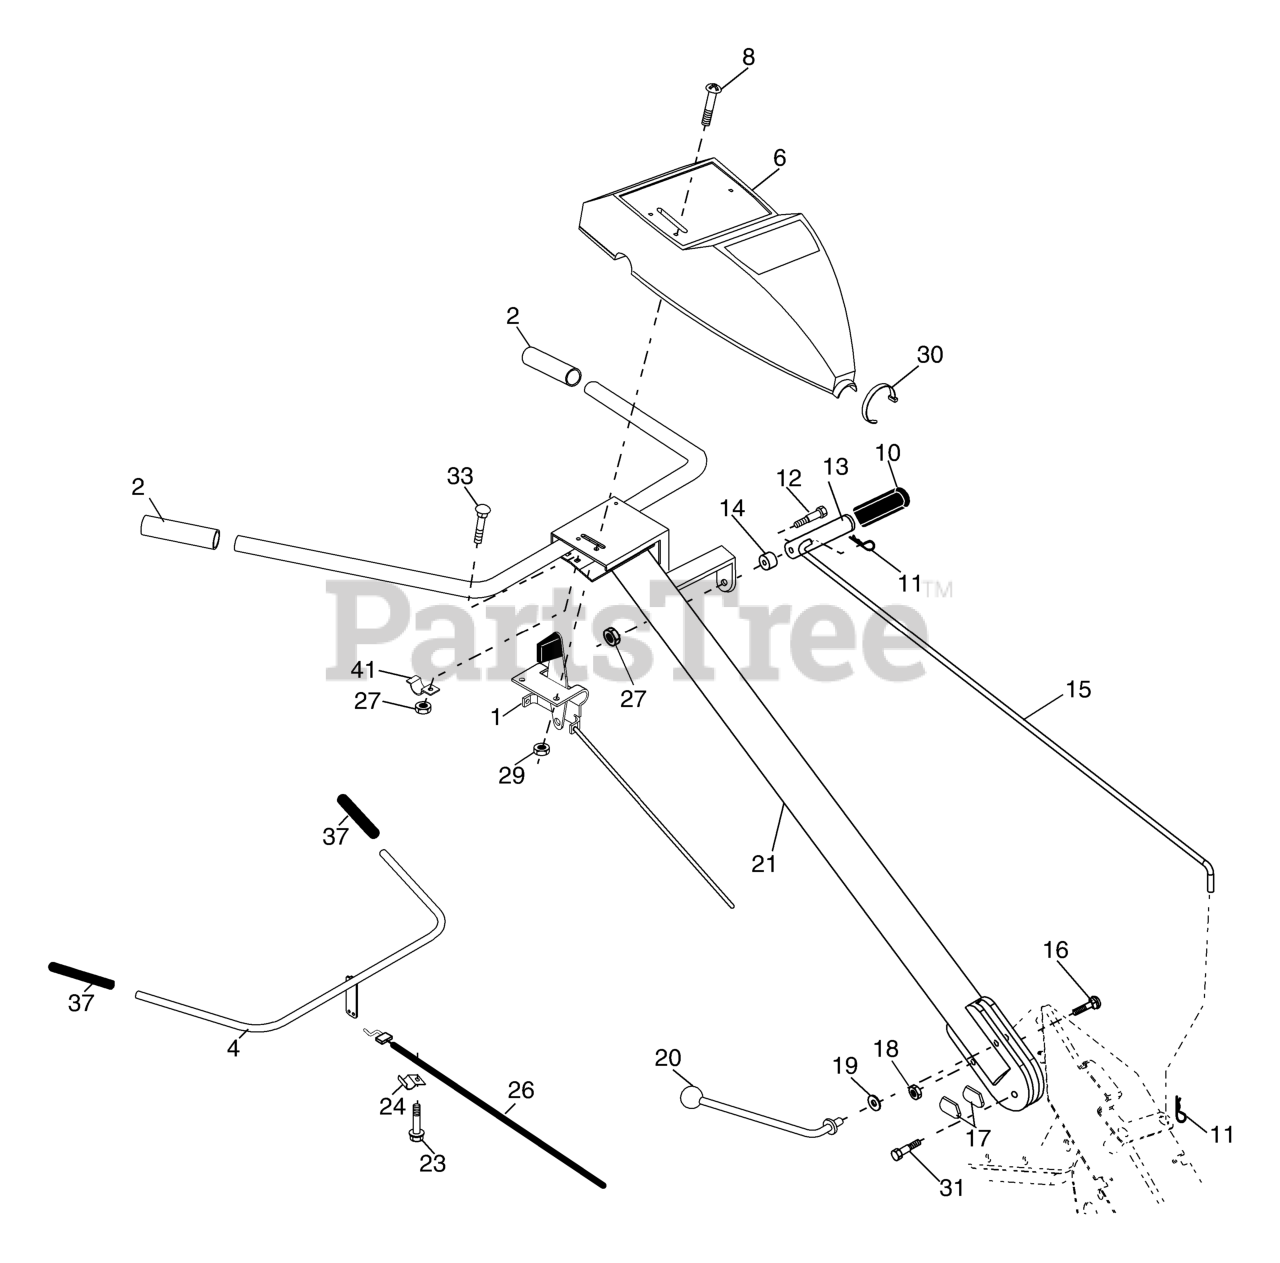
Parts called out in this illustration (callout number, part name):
1	THROTTLE.CONTROL.RT.INTEK.50
2	KIT.GRIP.HANDLE.5.00.BLK.VINYL
4	CONTROL BAR ASSY
6	RP CONTROL PANEL
8	SCREW.PNHD.10-24
10	GRIP T
11	RETAINER M
12	SHOULDER BOLT ST
13	HANDLE.SHIFT.TILLER
14	GROMMET.RUBBER.CRT.TILLER
15	SHIFT ROD CRT
16	BOLT D
17	LOCK.HANDLE.CRT
19	WASHER CRT
20	LEVER.LOCK.CRT
21	REPL BY 532 1805-17
23	TAPPING SCREW
24	CONDUIT.CLIP.PLATED
26	CABLE.CLUTCH
27	NUT T
29	NUT **
30	TIE CABLE CRT
31	BOLT.PIVOT
33	BOLT
37	GRIP BAR CRT(1)
41	CLAMP.BAR.CRT.BLACK
